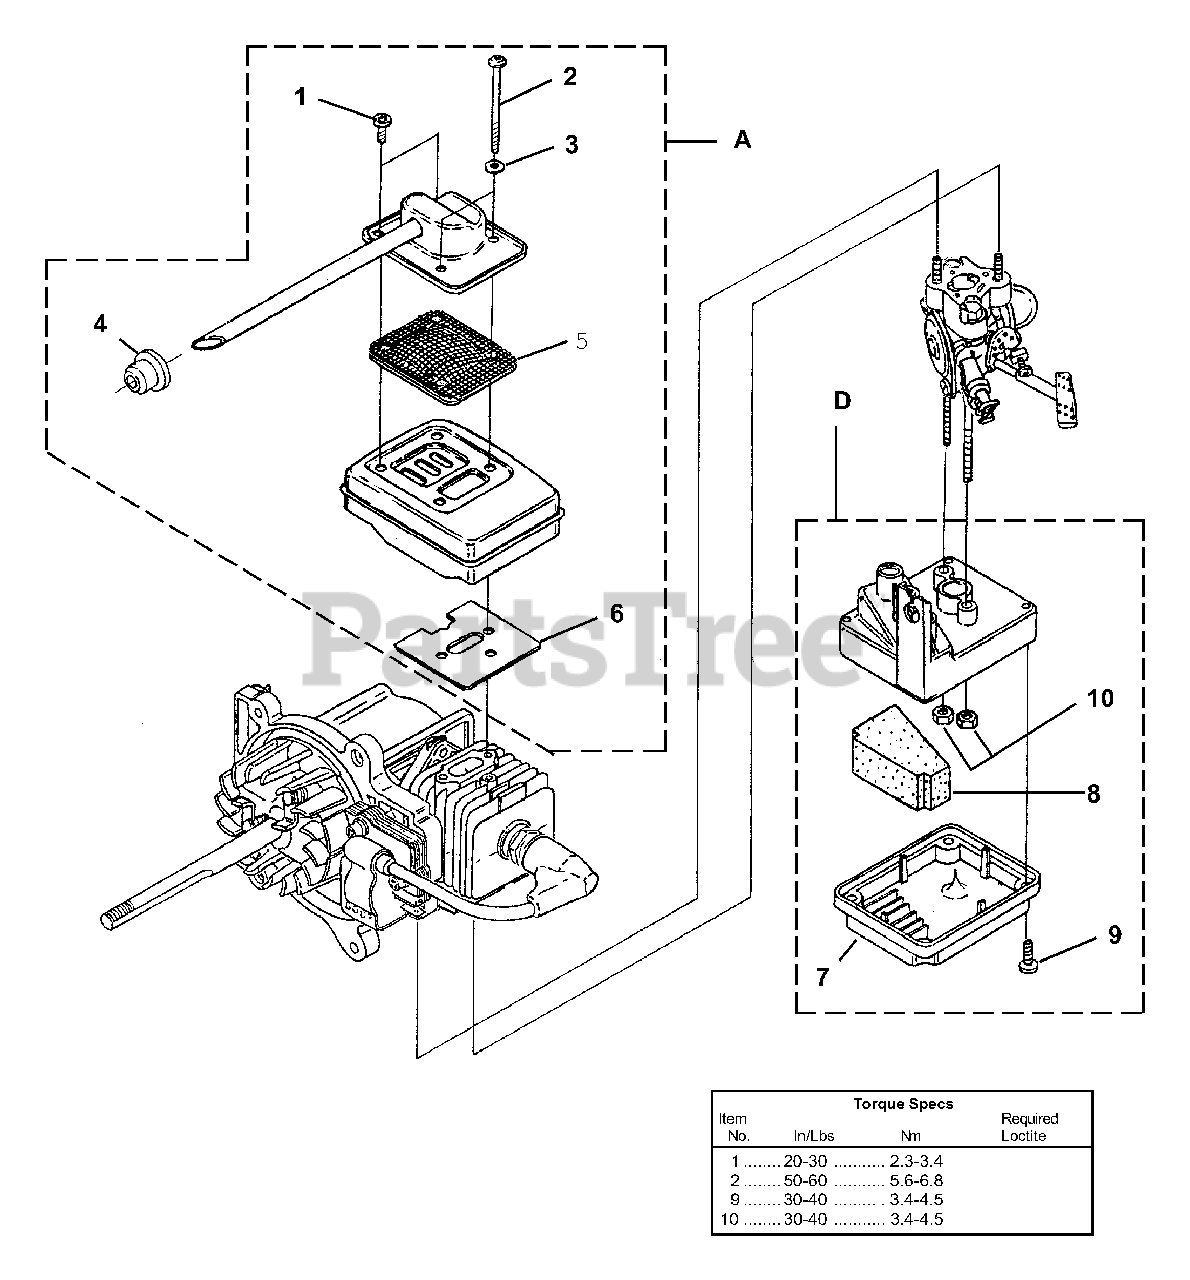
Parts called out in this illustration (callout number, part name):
1	Screw, Taptite (8-32 x 3/8)
2	Screw, Torx Truss Hd. (10-24 X 2.188")
3	Washer, Conical #10
4	Muffler Grommet
5	Screen Assy., Spark
6	Gasket, Muffler
7	Cover, Air Box
8	Filter Element #1
9	Screw, Thread Forming (8-16 X .50)
10	Nut, Lock Hex (10-24)
A	Muffler Assembly, Crimped
D	Air Filter Assembly
